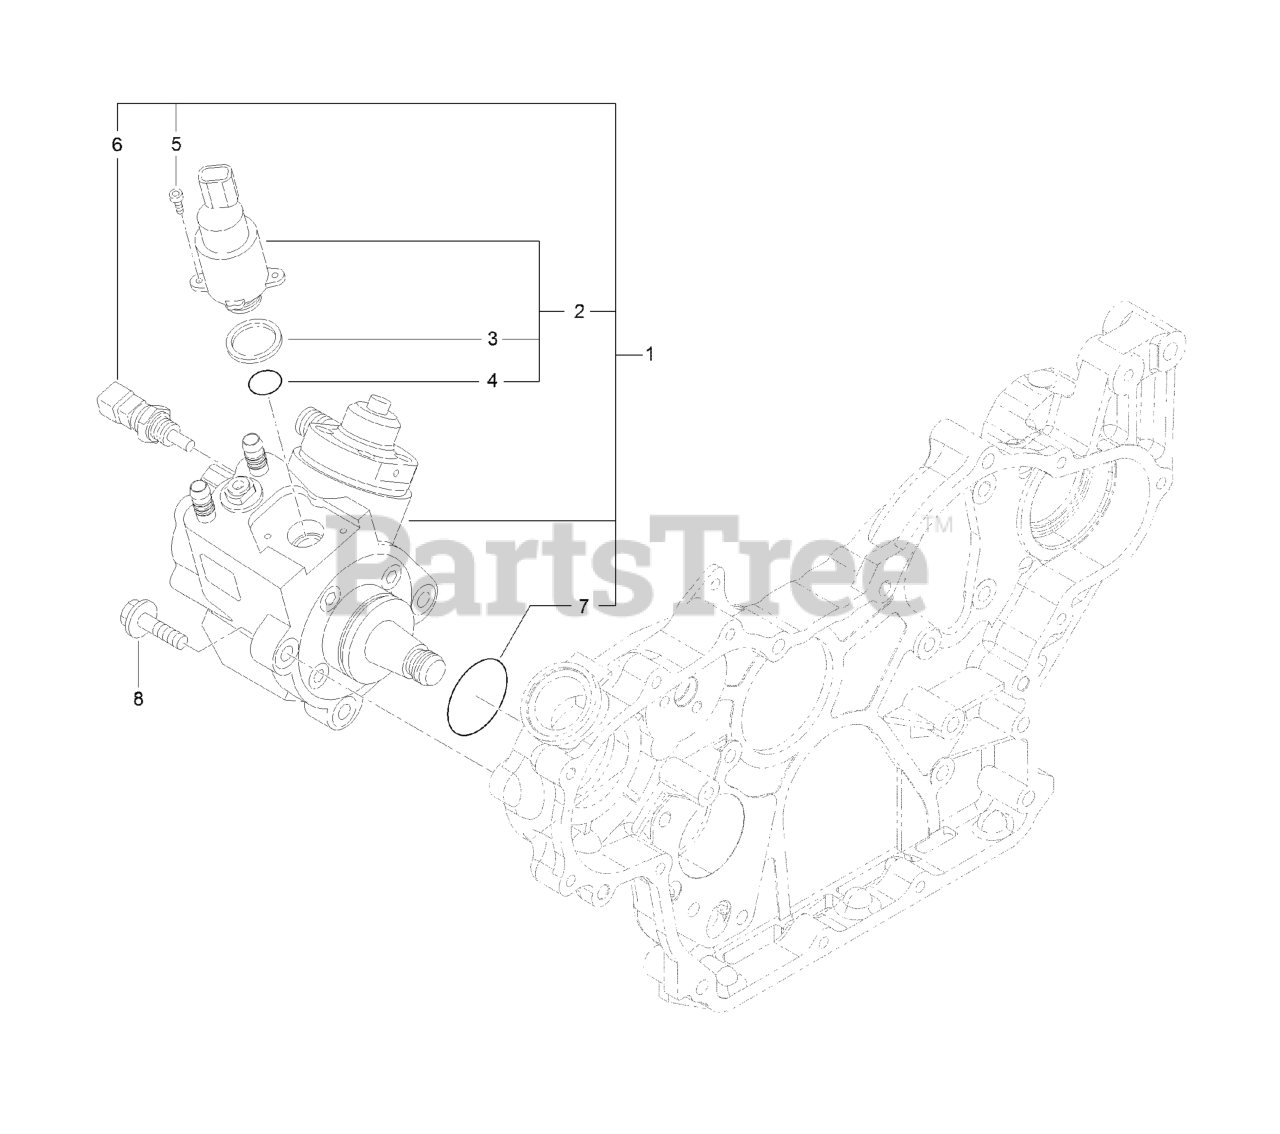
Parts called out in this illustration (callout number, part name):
1	FUEL PUMP ASM
2	VALVE ASM
3	RING-SEALING
6	SENSOR-TEMPERATURE
